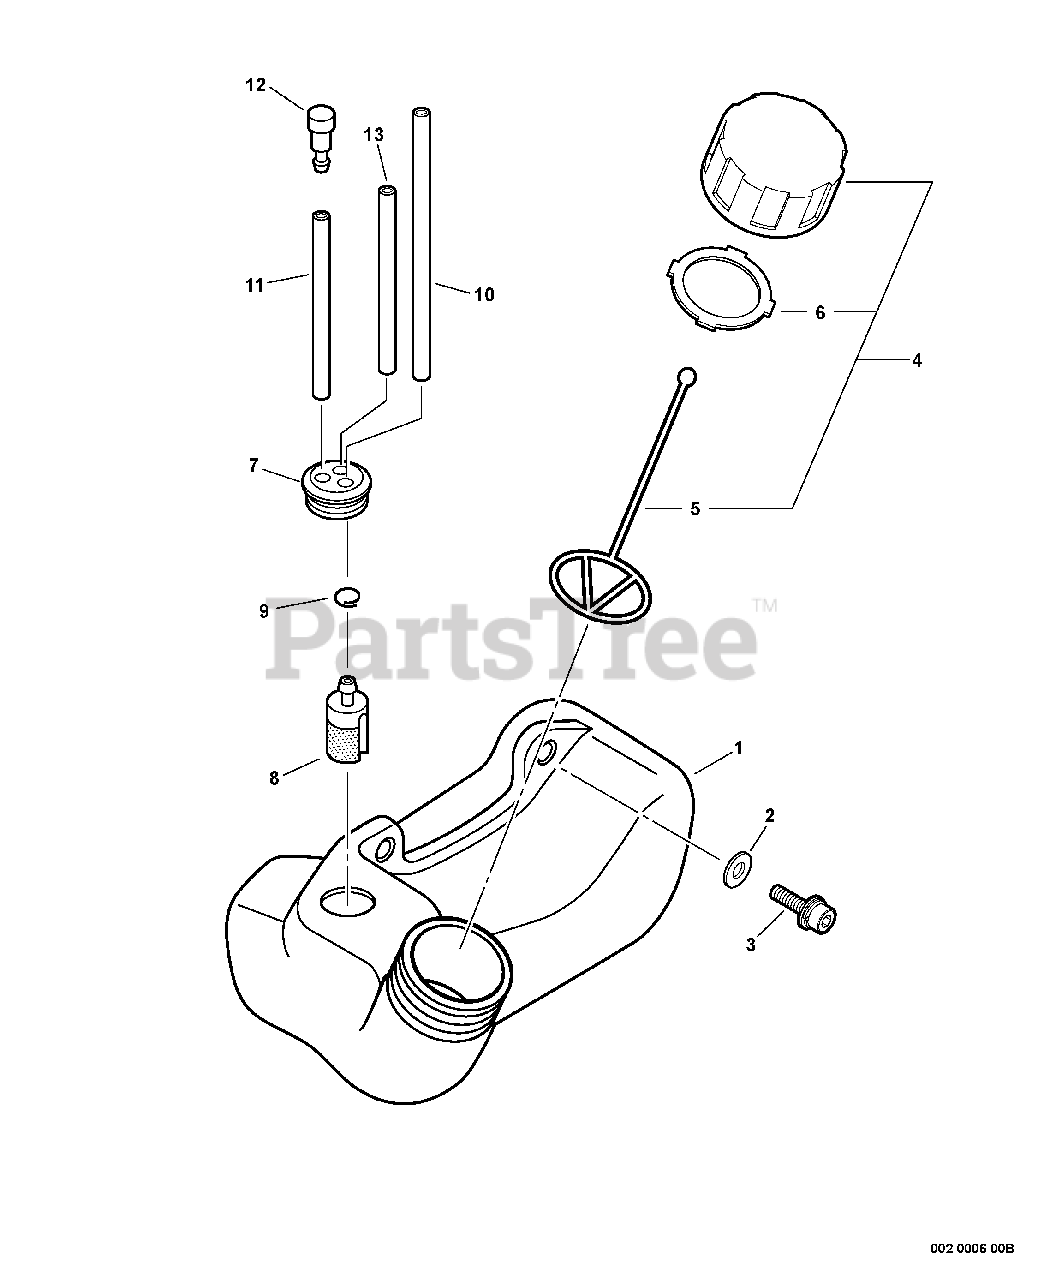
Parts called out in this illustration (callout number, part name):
1	TANK, FUEL
2	WASHER - 5
3	SCREW - 5X20
4	CAP ASSY - ORANGE
5	CONNECTOR, CAP
6	GASKET, CAP
7	GROMMET
8	FILTER, FUEL
9	CLIP - 6
10	PIPE - 3X5X180 -- BLACK
11	PIPE - 3X5X70 -- BLACK
12	VENT, FUEL TANK
13	PIPE - 3X6X80 -- CLEAR
